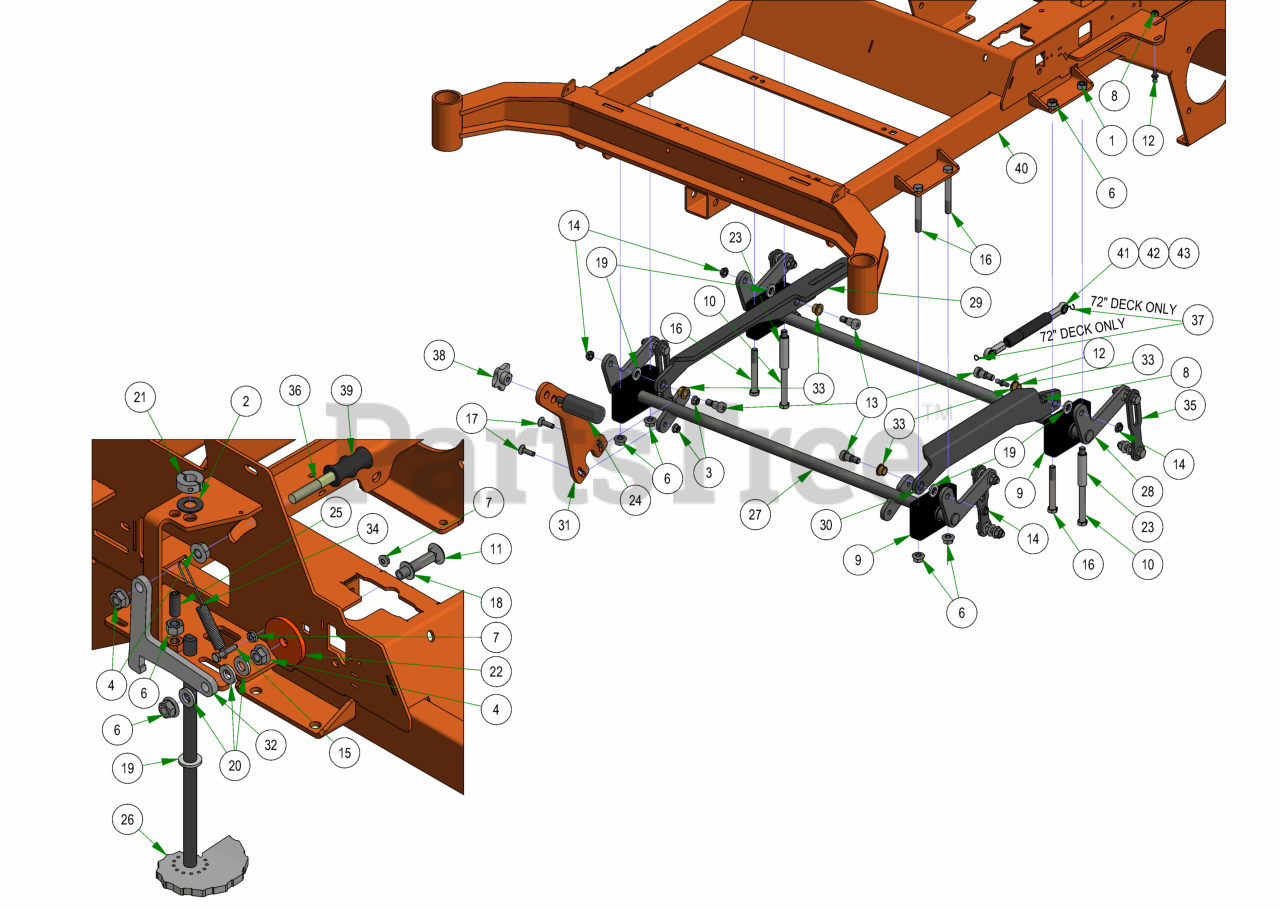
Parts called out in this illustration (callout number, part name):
1	1/2-13 HEX 2-WAY REVERSIBLE CENTER LOCKNUT Grade B ZINC
2	.625 ID x 1.250 OD x .062 THK F/W Nylon
3	3/8-16 NYLON INSERT FLANGE LOCKNUT (GR.F) ZINC
4	1/2-13 HEX SERRATED FLANGE NUT HARD/ZINC
6	1/2-13 HEX NUT ZINC
6	1/2-13 NYLON INSERT FLANGE LOCKNUT ZINC
7	1/4-20 HEX SERRATED FLANGE NUT HARD/ZINC
8	5/16-18 HEX SERRATED FLANGE NUT HARD/ZINC
9	Pillow Block Assembly
10	1/2-13 X 7 HEX CAP SCREW (GR.5) ZINC
11	2 1/2 x 1/2 Carriage Bolt
12	10mm Damper Ball Stud-XP Linkage
13	5/8 X 5/8 SOCKET SHOULDER BOLT ZINC YELLOW
14	1/2-13 NYLON INSERT JAM LOCKNUT ZINC
15	1/4-20 X 1-1/4 HEX CAP SCREW (GR.5) ZINC
16	1/2-13 X 4 HEX CAP SCREW (GR.8) ZINC YELLOW
17	3/8-16 X 1-1/4 CARRIAGE BOLT ZINC
18	.517 SQ WDTH ID X .937 OD X .060 THICK F/W PHOS/OIL
19	.635 ID X 1.120 OD X .140 THICK FLAT WASHER NYLON
20	.505 ID X 1.000 OD X .125 THICK FLAT WASHER NYLON
21	5/8" Split Collar
22	MZ Deck Idler Spacer
23	2019 Deck Stop Spacer
24	Knurled Pedal
25	Dial Rod Plunger
26	2019 Outlaw Gen2 Deck Height Dial Rod Assy
27	2019 Outlaw Actuator - Front
28	2019 Outlaw Actuator - Rear
29	2019 Actuator Linkage – Right – Black
30	2019 Actuator Linkage - Left - Black
31	Foot Lift Upright Lever
32	2019 Outlaw Deck Travel Lock
33	.627 ID X .753 OD X .500 LGTH X 1.000 FLG OD X .094 FLG THICK FLANGED BEARING OIL-IMPREG BRNZ
34	Brake Spring
35	Deck Hanger Assembly
36	Seat Bracket Pin
37	Security Ring - PC744
38	Foot Pedal Knob 1/2-13
39	Travel Lock Rubber Grip
40	2023 Rebel Frame - Painted
41	200 lb Gas Spring- 54" Deck outlaw
42	250lb Gas Spring - 61" Deck
43	300lb Gas Spring - 72" Deck
